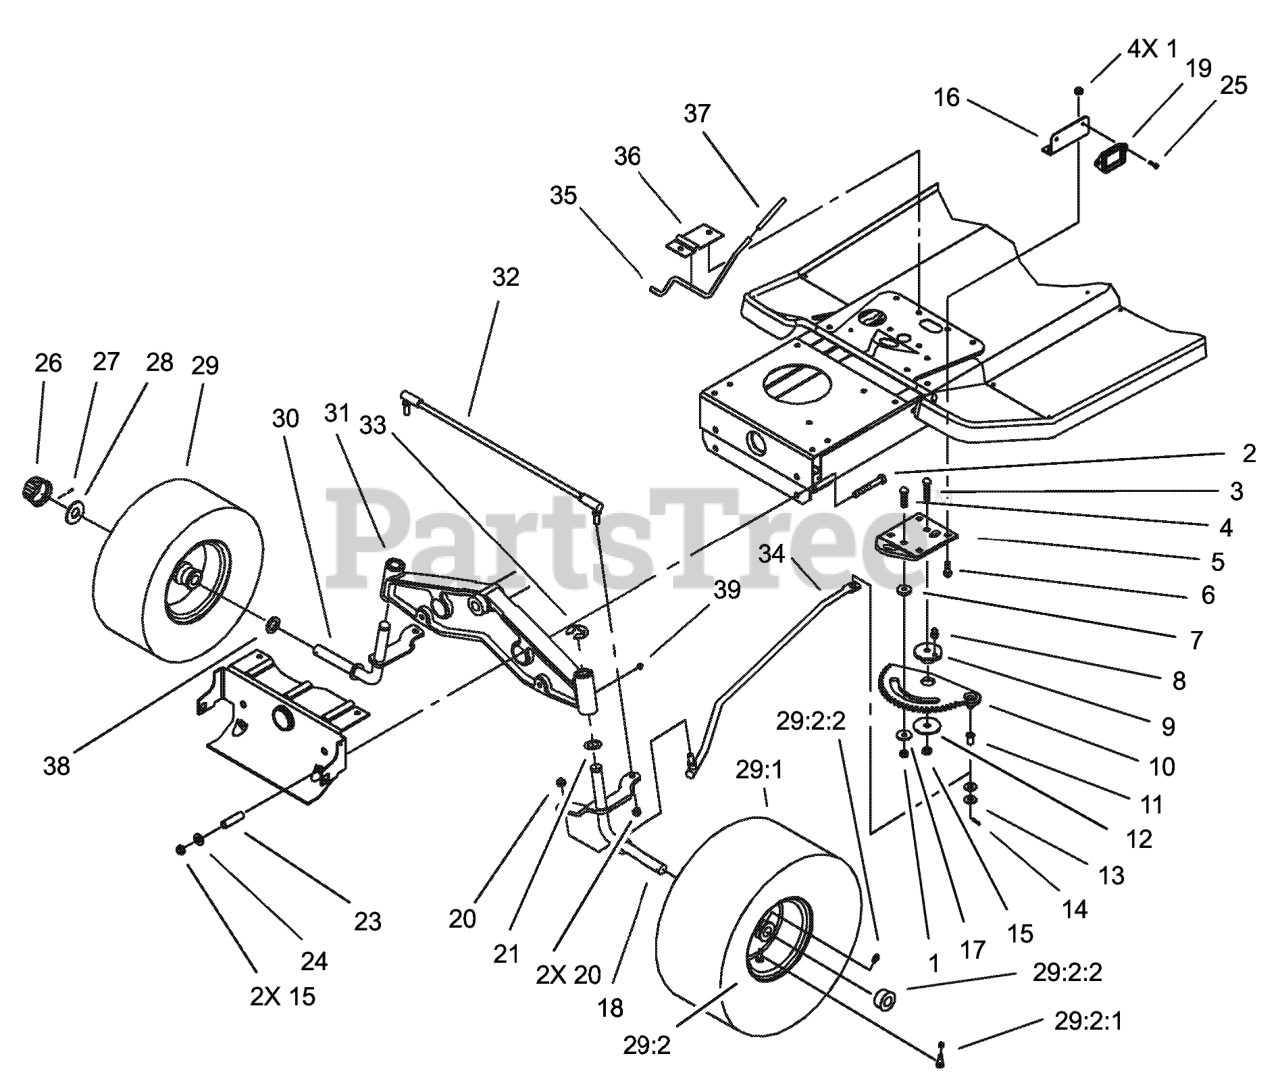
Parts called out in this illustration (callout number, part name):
1	NUT-LOCK, NI
2	SCREW-HH
3	SCREW-CARR
4	SCREW-CARR
5	BRACKET-RACK, STEERING
6	BOLT-CARR
7	SPACER-RACK, STEERING
8	FITTING-GREASE
9	BUSHING-ECCENTRIC
10	RACK-STEERING
11	BUSHING-FLANGED, NYLON
12	WASHER-BEARING
13	WASHER-FLAT
14	PIN-COTTER
15	NUT-LOCK, NI
16	BRACKET-MODULE
17	WASHER-PIVOT
18	SPINDLE-LH
19	MODULE
20	NUT-HEX
21	WASHER-THRUST
23	SPACER
24	WASHER-FLAT
25	SCREW-HWH
26	CAP-HUB
27	PIN-COTTER
28	WASHER-PLAIN
29	Front Wheelandtire ASM
29:2:1	STEM-VALVE
29:2:2	BEARING-WHEEL
29:2:3	FITTING-GREASE
30	RH SPINDLE ASM
31	AXLE-FRONT
32	TIE ROD ASM
33	E-RING
34	LINK-DRAG
35	ROD-BRAKE, PARKING
36	BRACKET-PARKING BRAKE
37	GRIP-BRAKE, PARKING
38	WASHER-THRUST
39	FITTING-GREASE
